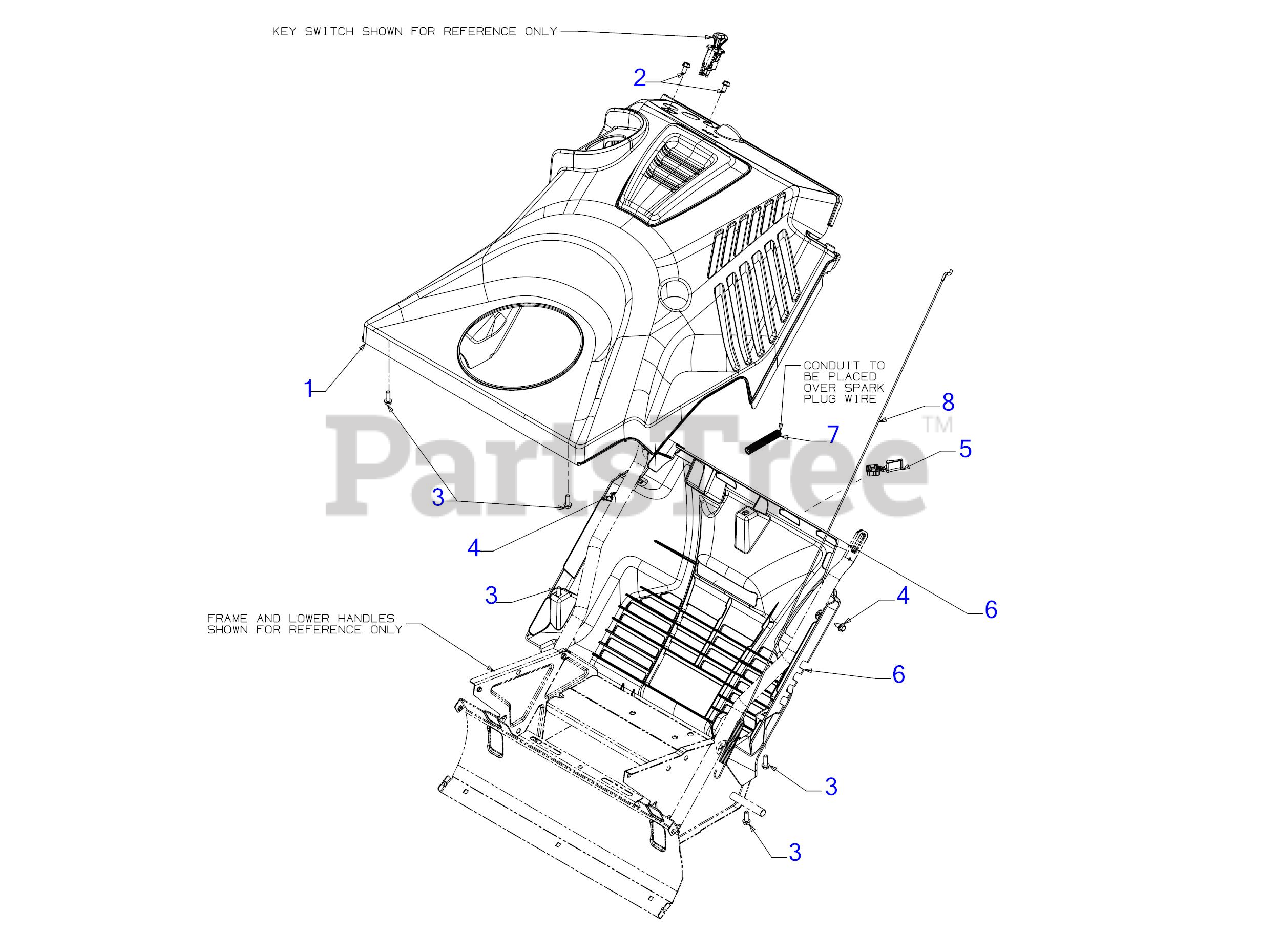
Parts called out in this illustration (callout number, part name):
1	COVER ASSEMBLY
2	HEX SCREW 1/4-15 x .50
3	SCREW 1/4-15 x .750
4	SCREW 1/4-20X.625
5	CHOKE EXTENION LEVER
6	BOTTOM COVER
7	CONVOLUTED CONDUIT
8	AUGER CLUTCH CABLE 37.05"
